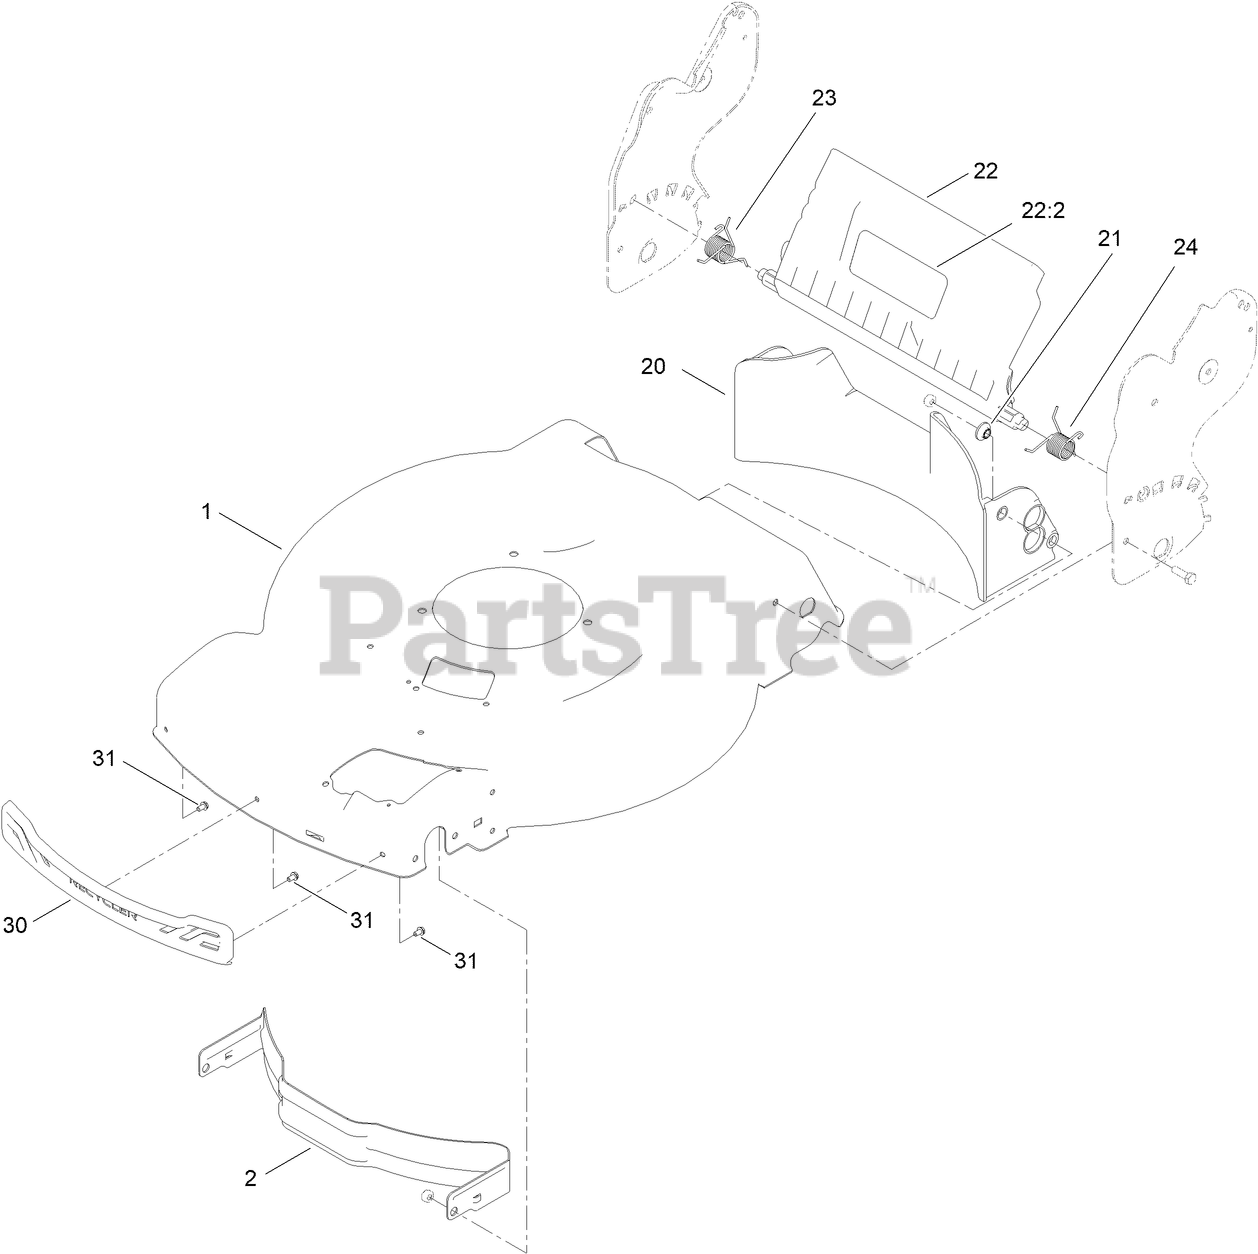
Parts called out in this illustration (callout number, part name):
1	HOUSING ASM
2	BAFFLE-FRONT
20	BAFFLE-REAR, FWD
21	WASHER-STEPPED, BAFFLE
22	REAR DEFLECTOR ASM
22:2	DECAL-WARNING
23	SPRING-TORSION
24	SPRING-TORSION
30	BUMPER-FRONT
31	SCREW-PLASTIC, HWH
